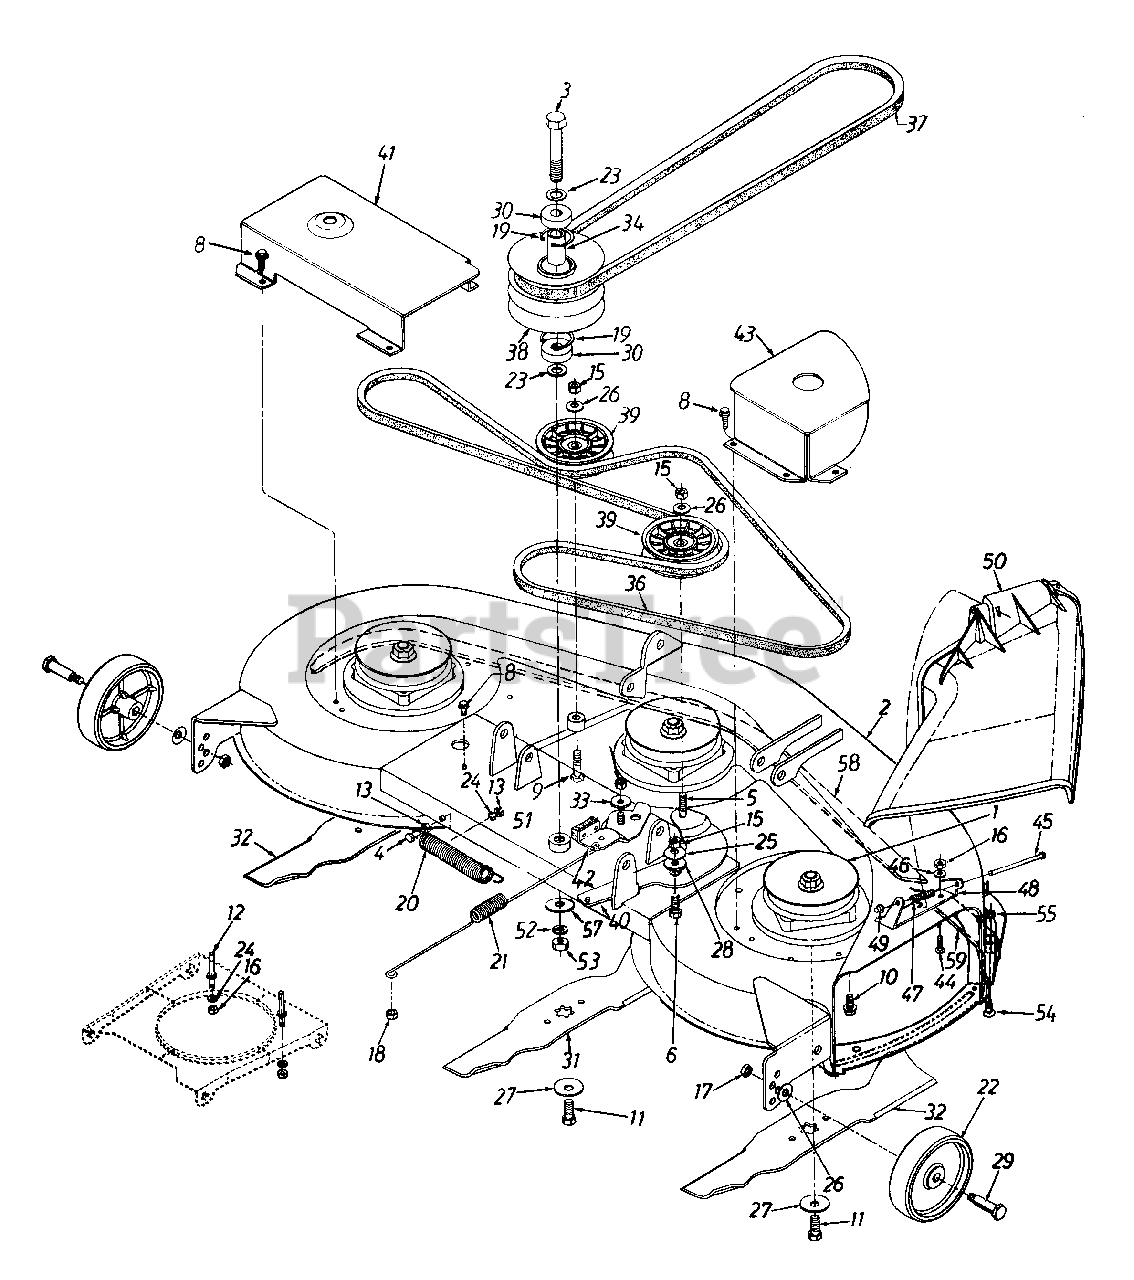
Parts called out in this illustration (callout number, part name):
1	Blade Spindle Ass'y.
4	Hex Bolt 1/4-28 x 1.25" Lg.
5	Hex Bolt 3/8-24 x 1.5" Lg.
6	Hex Bolt 3/8-24 x 1" Lg.
8	Hex Wash. Hd. TT-Tap Scr. 1/4-20 x .5" Lg.
9	Hex Bolt 3/8-24 x 2" Lg.
10	Hex Flange Bolt 5/16-24 x .75" Lg.
11	Hex Patch L-Bolt 7/16-20 x 1" Lg.
12	Belt Guard Pin
13	Hex Nut 1/4-28 Thd.
14	Hex Ins. L-Nut 5/16-18 Thd.
15	Hex Nut 3/8-24 Thd.
16	Hex Nut 1/4-20 Thd.
17	Hex Top Jam Nut 3/8-16 Thd.
18	Hex Patch L-Nut 5/16-18 Thd.
19	Int. Snap Ring
20	Ext. Spring .88" O.D. x 6.17"
21	Ext. Spring .788" O.D. x 15.5"
22	Deck Wheel
23	Fl-Wash. .635" I.D. x 1" O.D. x .06"
24	L-Wash. 1/4" I.D.
25	Bell-Wash. 3/8" x 1.125" x .062"
26	Bell-Wash. 3/8" x .87" x .064"
27	Bell-Washer
28	Shoulder Spacer .625" I.D. x .169"
29	Shld. Bolt .498" x 1.525"
30	Ball Brg. .625" I.D. x 1.574" O.D. x .47"
31	High Lift Blade 14.88" Lg.
32	High Lift Blade 16.28" Lg.
33	Shoulder Spacer
34	Spacer .635" I.D. x .088" O.D.
36	V-Belt
37	V-Belt
38	Pulley Double Deck 5" O.D.
39	Flat Idler Pulley 3.5 O.D.
44	Hex Bolt 1/4-20 x .62" Lg.
45	Hinge Pin
46	Bell-Wash. 1/4" I.D.
47	Torsion Spring
48	Hinge Mtg. Brkt.
49	Push Nut
50	Chute Ass'y. Comp.
51	Spacer .635" I.D. x 1" O.D.
52	L-Wash. 5/8" I.D.
53	Hex Nut 5/8-18 Thd.
54	Carriage Bolt 1/4-20 x .5 Lg.
55	Hex Sems Nut 1/4-20 Thd.
57	Fl-Wash. .635" I.D.
